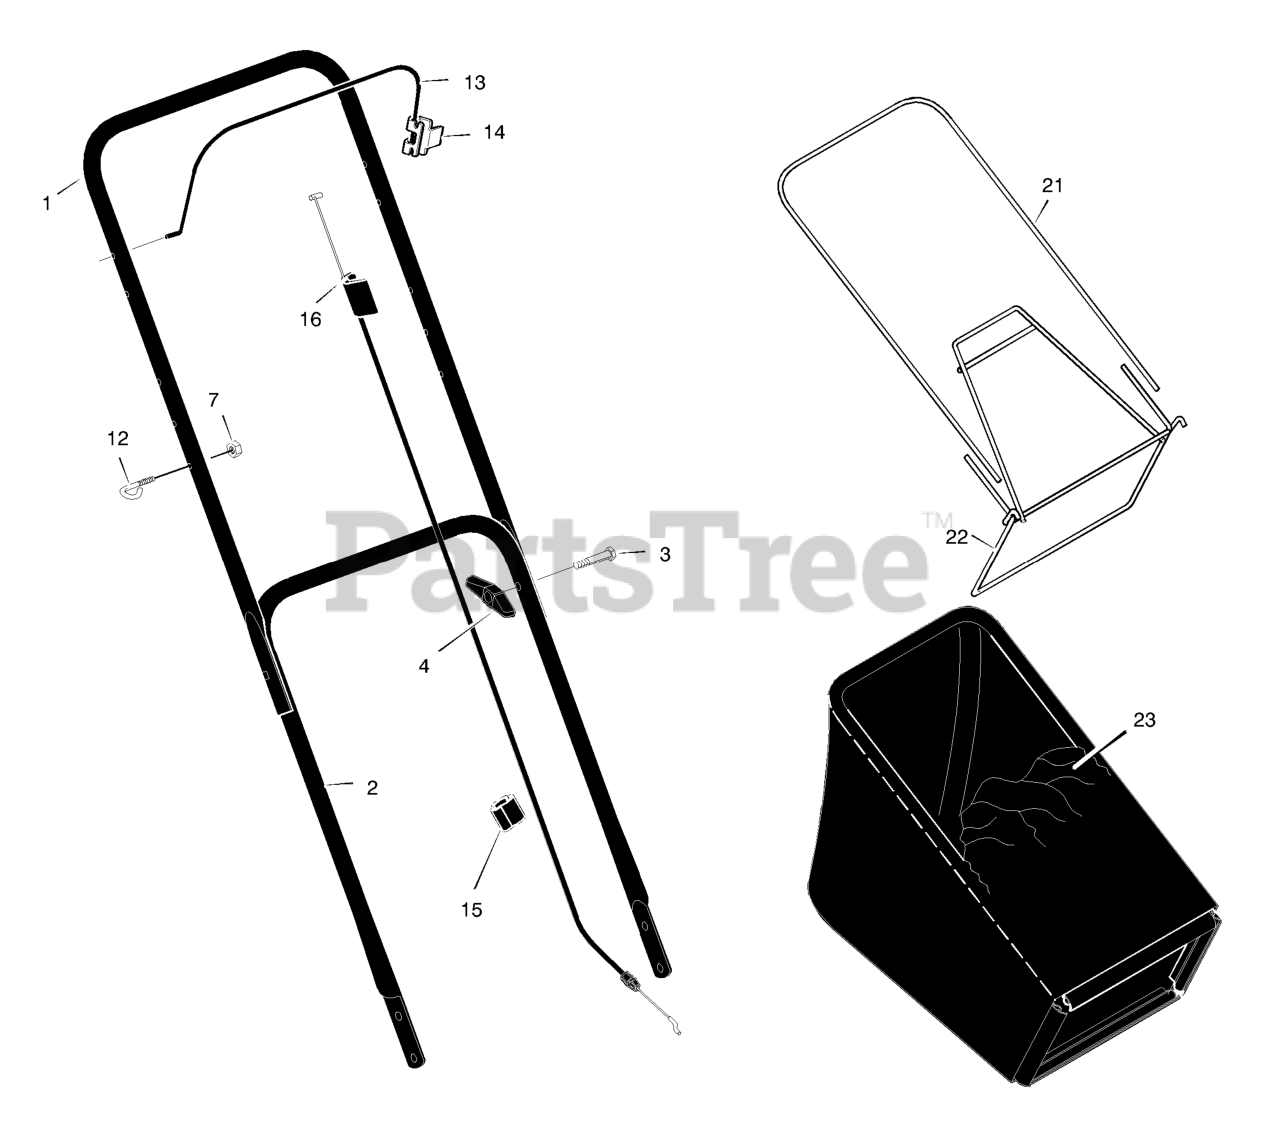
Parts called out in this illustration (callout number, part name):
1	Handle, Upper (Black)
2	Handle, Lower (Black)
4	Knob, Plastic
7	Locknut
12	Guide, Rope
13	Engine Stop Lever
14	Bracket, Stop Lever
15	Fastener, Cable
16	Engine Stop Cable
21	Frame, Top
22	Frame Assembly
23	Bag, Cloth
